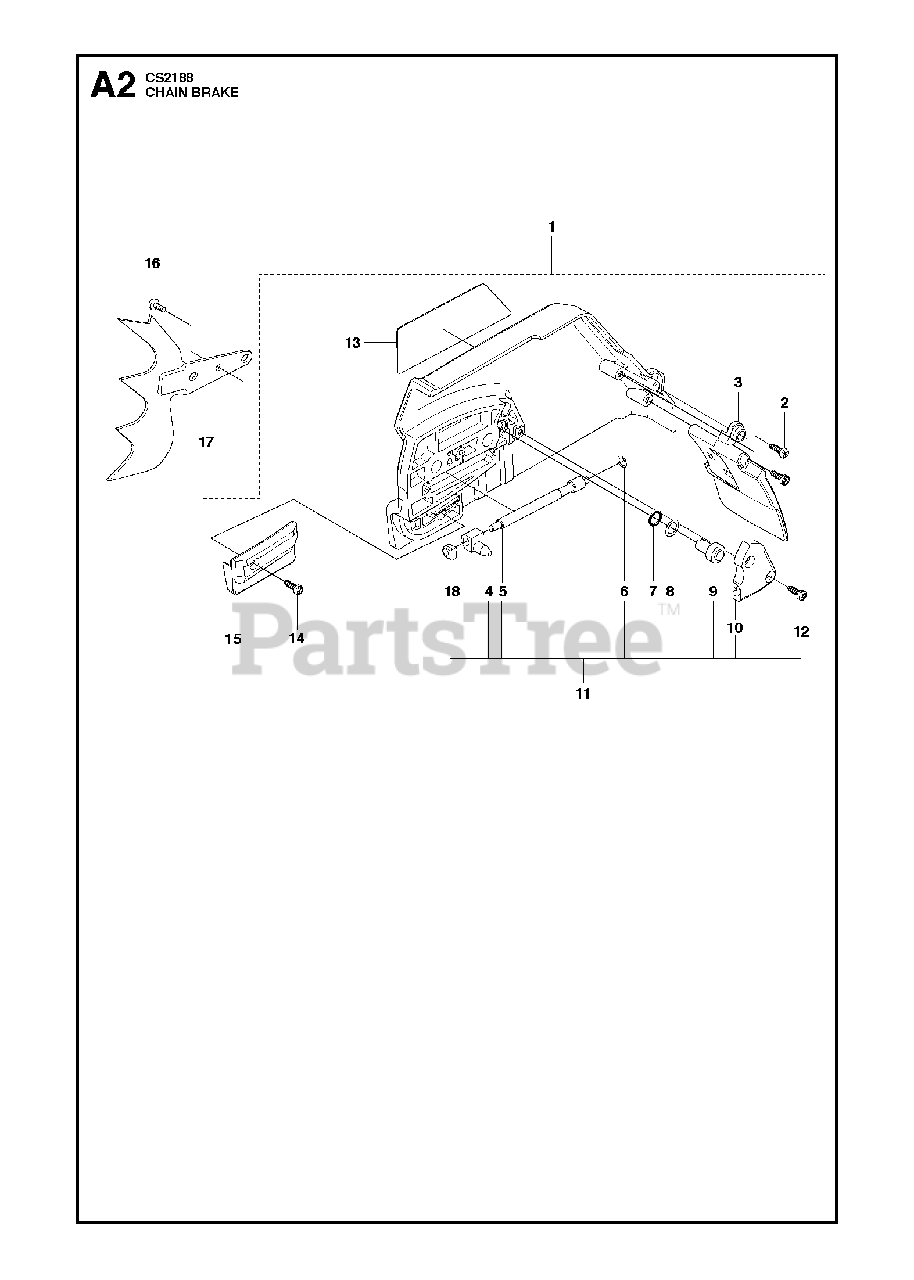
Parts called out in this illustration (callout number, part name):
1	CLUTCH COVER
2	SCREW
3	PROTECTOR
4	COUPLING
5	WORM SCREW / ADJUSTER
6	WASHER
7	O-RING
8	WASHER
9	SCREW
10	COVER
11	KIT-CHAIN TENSIONER
12	SCREW
13	DECAL
14	SCREW
15	CHAIN GUIDE
17	FELLING DOG
18	SLEEVE
